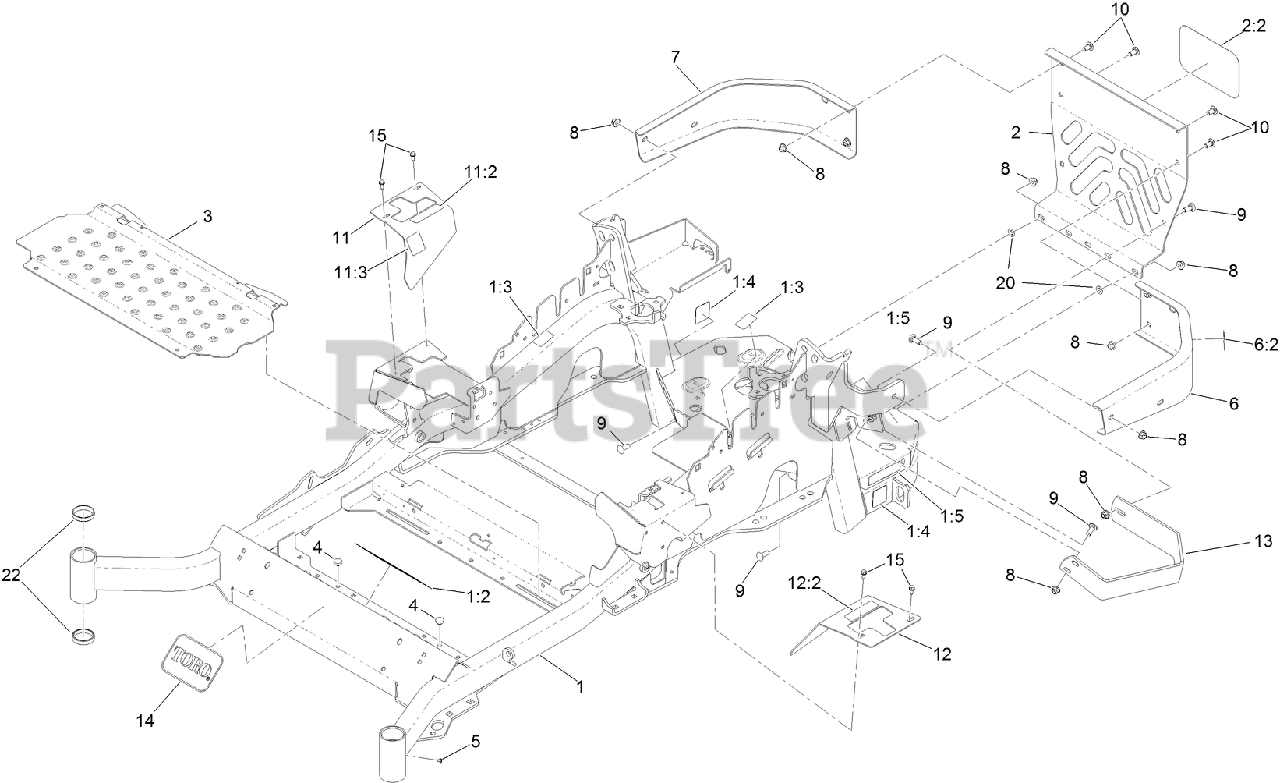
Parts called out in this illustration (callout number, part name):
1	MAINFRAME ASM
1:2	DECAL-DANGER
1:3	DECAL-WARNING
1:4	DECAL-HAZARD, PINCHED FINGER
1:5	DECAL-ARRESTOR, SPARK
2	REAR GUARD ASM
2:2	DECAL
3	FLOORPAN
4	BUMPER
6	LH BUMPER ASM
6:2	DECAL-WARNING
7	BUMPER-RH
8	NUT-HF, NI
9	SCREW-CARR
10	SCREW-CARR
11	RH MOTION CONTROL COVER ASM
11:2	DECAL-CONTROL, MOTION
11:3	DECAL-PARK BRAKE, CE
12	LH MOTION CONTROL COVER ASM
12:2	DECAL-CONTROL, MOTION
13	GUARD-MUFFLER
14	DECAL
15	SCREW-HWH
20	NUT-PUSH
22	CUP-BEARING
